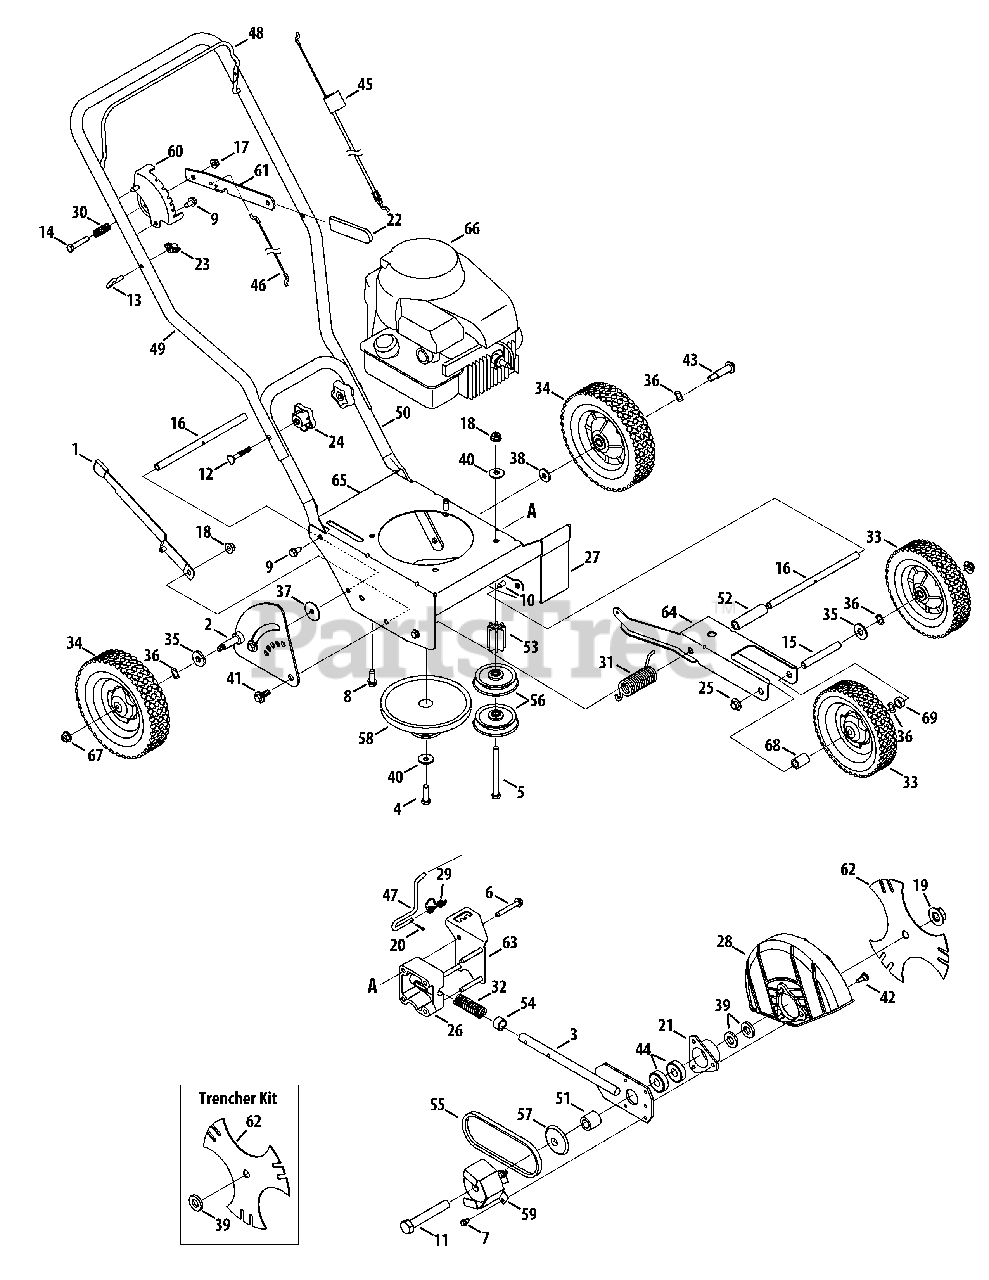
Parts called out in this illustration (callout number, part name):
1	Curb Height Adjustment Lever
2	Curb Height Adjuster Plate
3	Blade Plate Assembly
4	Screw 3/8-24
5	Screw 3/8-16
6	Hex Screw, 5/16-18
7	Self-tapping Screw, 1/4-20
8	Screw, 3/8-16
9	Hex Screw, 5/16-12
10	Hex Screw 5/16-18
11	Hex Screw, 5/8-18
12	Carriage Bolt, 5/16-18
13	Rope Guide (Eye Bolt)
14	Hex Screw, 5/16-18
15	Axle Shaft .50x6.65
16	Frame Spacer .50x9.25
17	Lock Flange Nut, 5/16-18
18	Flange Nut 3/8-16
19	Flange Nut, 5/8-18
20	Clevis Pin 3/32 x .625
21	Bearing Cup
23	Wing Nut
24	Star Knob
25	Push Cap 1/2" rod
26	Bearing Block
27	Debris Guard
28	Blade Guard
29	Double Torsion Spring
30	Compression Spring
31	Torsion Spring
32	Compression Spring
33	Wheel 7 x 1.75 T-Tread
34	Wheel 8 x 1.75 T-Tread
35	Flat Washer, .531 x 1.25 x .181
36	Wave Washer .531 x .781 x .013
37	Flat Washer, .385 x 1.5 x .075
38	Flat Washer .385 x 1.0 x .135 †
39	Flat Washer .635x1.24x.181
40	Bell Washer,.396 x 1.140
41	Shoulder Screw, 3/8-16
42	Shoulder Screw
43	Shoulder Screw, 3/8-16
44	Bearing, .625 ID x 1.57 OD
45	Control Cable
46	Wheel Adjustment Cable
47	Blade Adjustment Rod
48	Bail Handle
49	Upper Handle
50	Lower Handle
51	Spacer, .63 x 1.12 x 1.06
52	Spacer
53	Pulley Mount Spacer
54	Spacer, .64 x.88 x .50
56	Flat Idler Pulley, 2.5 OD
57	Sheave
58	Combination Flywheel Pulley
59	Belt Guard
61	Depth Index Lever
62	Tri-Star Blade
63	Bracket Plate
64	Wheel Bracket
66	Engine - 10L802-5547-F2
67	Flange Lock Nut, 3/8-16
68	Spacer, .525 x .775 x .93
69	Spacer, .505ID x .88OD x .440
